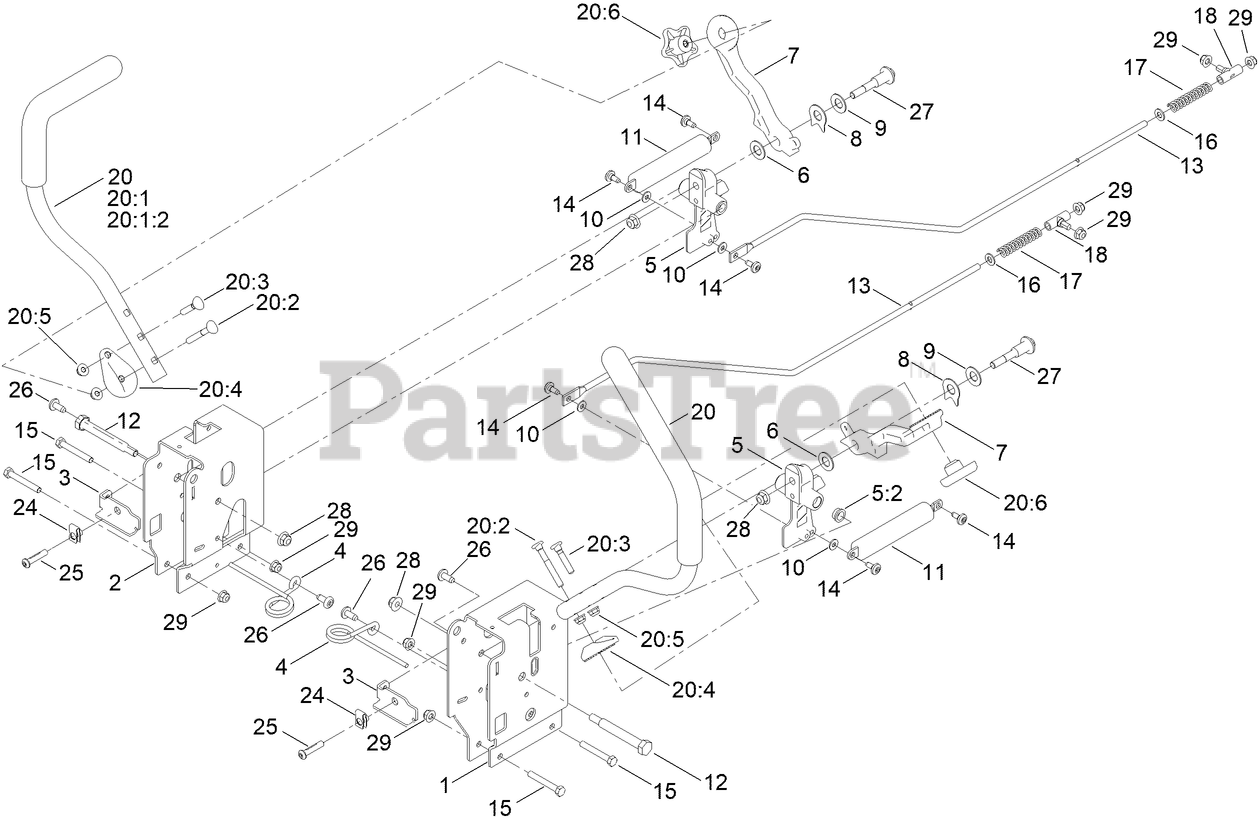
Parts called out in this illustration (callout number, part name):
1	CONTROL BOX - LH G7
2	CONTROL BOX - RH G7
3	ADJUSTMENT PLATE-CONTROL BOX
4	SPRING-TORSION
5	PIVOT ARM ASM
5:2	BUSHING-FLANGE
6	WASHER-NYLON
7	ARM-CONTROL, 32 TEETH
8	SPACER, ANTI-ROTATION
9	WASHER-BELLEVILLE
10	WASHER
11	DAMPER-NON CAVITATING
12	BOLT-PIVOT
13	ROD-HYDRO
14	SCREW-SHOULDER
15	SCREW-HH
16	WASHER-PLAIN
17	SPRING-COMPRESSION
18	MOUNT-ROD, HYDRO
20	HANDLE-CONTROL, ASM
20:1	HANDLE-CONTROL,
20:2	SCREW-HANDLE
20:3	SCREW-HANDLE
20:4	DISC-ADJUSTMENT HANDLE, 32 TEETH
20:5	NUT-HF
20:6	KNOB-HANDLE
25	SCREW-HSBH
27	BOLT-PIVOT
28	NUT-HF, NI
29	NUT-HF, NI
